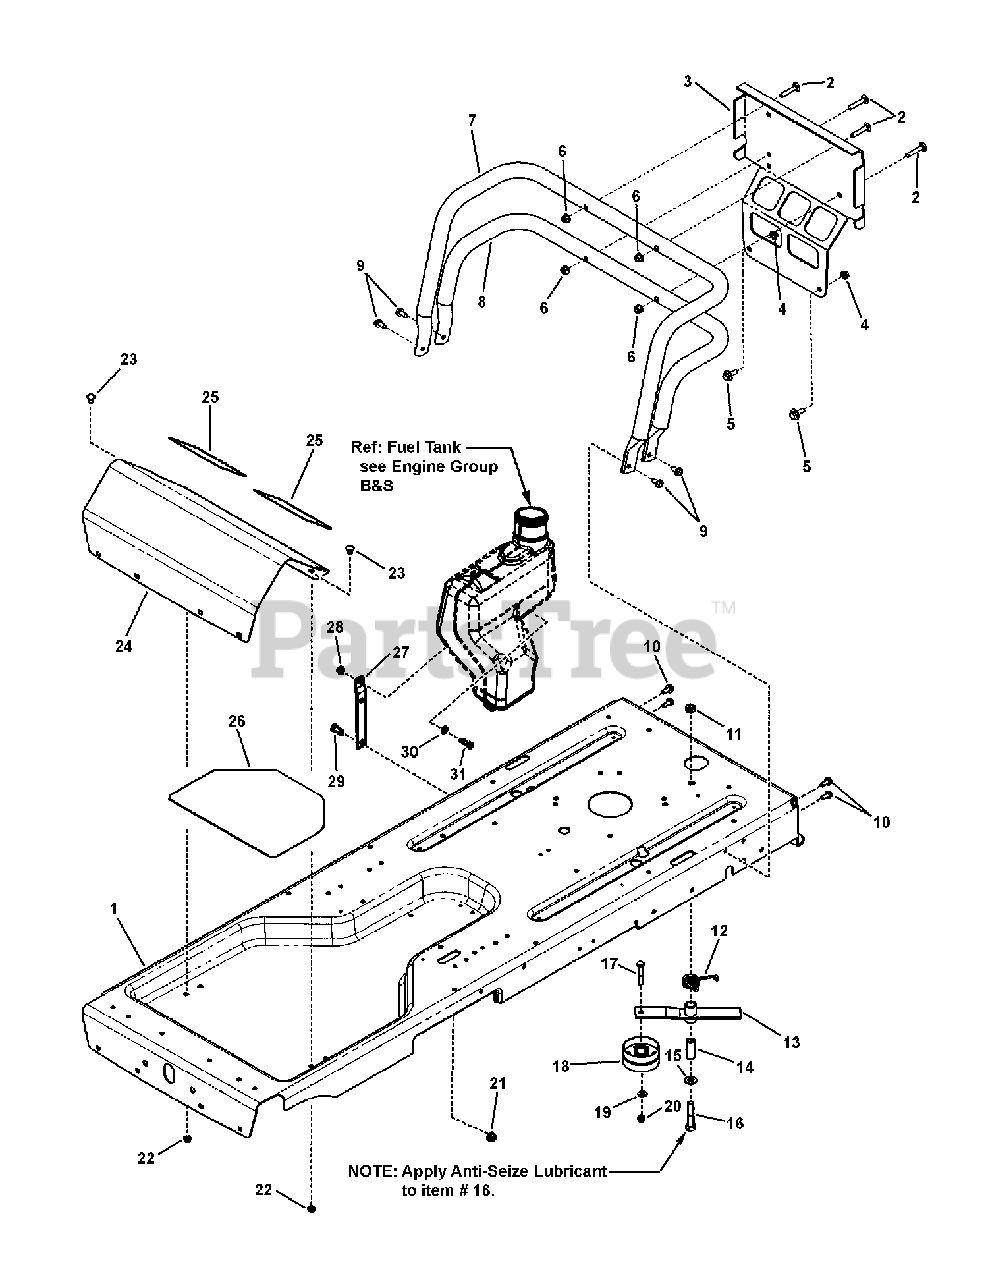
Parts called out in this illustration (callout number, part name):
1	FRAME, RZT
2	BOLT, 5/16-18 x 1-3/4" Round Head Short Square Neck, GR 5
3	PLATE, Brand
4	NUT, 5/16-18 Hex Flange Lock, Large, Black
5	SHOULDER BOLT, 5/16-18 x 3/4
6	NUT, 5/16-18 Hex Flange Nyloc
7	BUMPER TUBE, Upper
8	BUMPER TUBE, Lower
9	SCREW, 5/16-18 x 3/4" Hex Washer Self-Tap, Black
10	SCREW, 5/16-18 x 3/4" Hex Washer Self-Tap, YZ
11	NUT, 1/2-13 Hex Center Lock, GR 5, YZ
12	SPRING, Torsion, RH Wind
13	WELDMENT, Hydro Idler
14	SPACER, Hydro Idler
15	WASHER, 1/2" Flat
16	SCREW, 1/2-13 x 2-1/2" Hex Head Cap, GR 5, BP
17	SCREW, 3/8-16 x 2" Hex Head Cap, GR 5, YZ
18	IDLER, 3.25 OD x.391 ID x 1.63, Backside
19	WASHER, 3/8" Flat (SAE)
20	NUT, 3/8-16 Hex Center Lock, GR 5, YZ
21	NUT, 3/8-16 Hex Flange lock, GR F, BZ
22	NUT, 5/16-18 Hex Flange Lock, GR 5, YZ
23	BOLT, 5/16-18 x 5/8" Round Head Short Square Neck, GR 5, YZ
24	FOOTREST, SNAPPER
25	FOOT PAD, Wide
26	MAT, Floor Pan
27	BRACKET, Support, Fuel Tank
28	NUT, 5/16-18 Hex Nyloc, YZ
29	SCREW, 3/8-16 x 3/4" Hex Head Cap, GR 5, ZP
30	WASHER, 5/16" Flat
31	SCREW, 5/16-18 x 1" Hex Head Cap, GR 5, YZ
